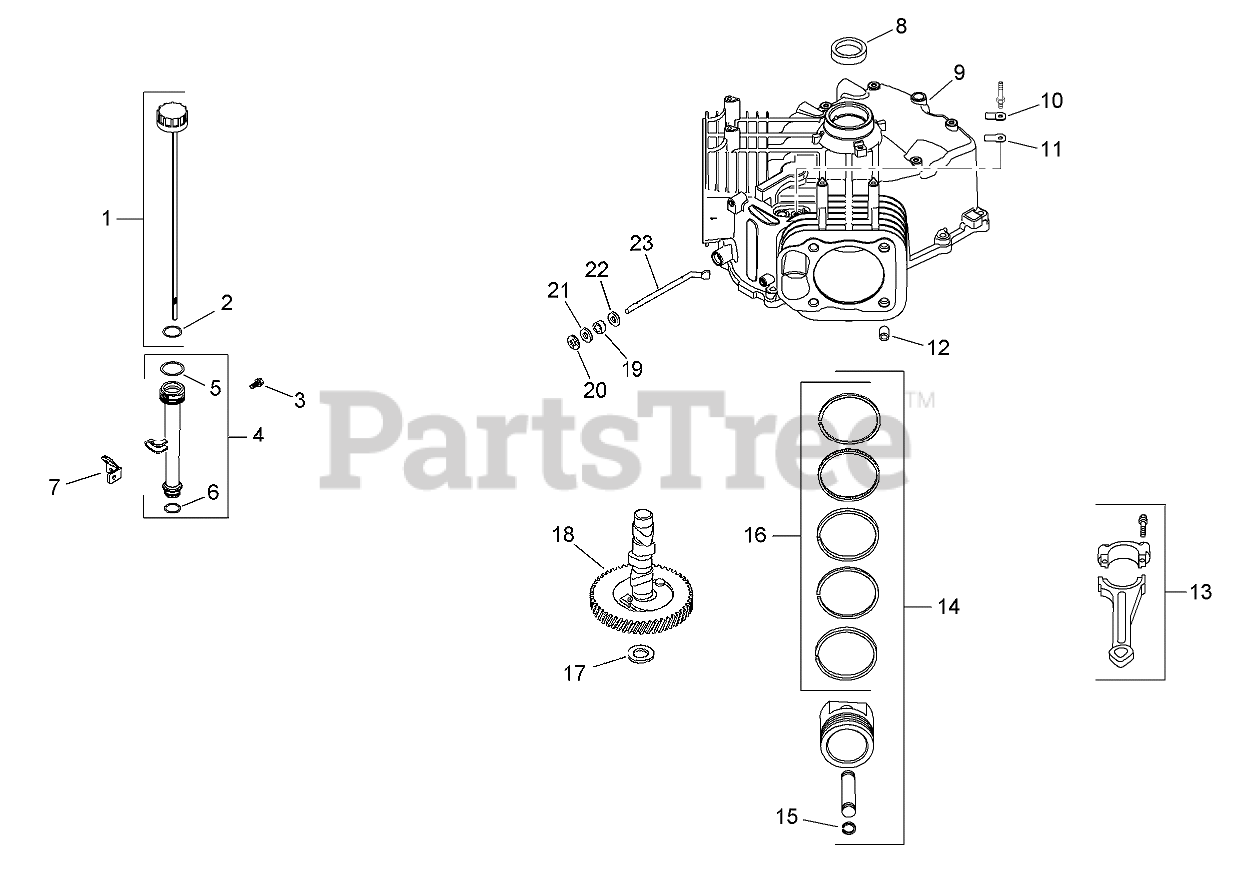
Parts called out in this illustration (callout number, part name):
1	Dipstick ASM (INCLUDES 21, 22)
2	O-RING (DIPSTICK)
3	SCREW-FLG, THD FRM (M5X0.8X13)
4	OIL FILL TUBE KIT
5	O-RING (UPPER OIL FILL TUBE)
6	O-RING (LOWER OIL FILL TUBE)
7	BRACKET-TUBE, OIL FILL
8	SEAL-OIL (HELIX LIP)
9	SHORTBLOCK (SV710-740 REPLACEMENT)
10	RETAINER-REED, BREATHER
11	REED-BREATHER
12	PIN-LOCATING
13	ROD-CONNECTING (STD)
14	PISTON AND RING KIT (STD)
14	PISTON W/RING SET (.25)
14	PISTON W/RING SET (.08)
15	RETAINER-PIN, PISTON
16	Ring Set (.25)
16	Ring Set (STD)
17	SHIM-CAMSHAFT (WHITE .028)
17	SHIM-CAMSHAFT (BLUE .03)
17	SHIM-CAMSHAFT (RED .032)
17	SHIM-CAMSHAFT (YELLOW .034)
17	SHIM-CAMSHAFT (GREEN .036)
17	SHIM-CAMSHAFT (GRAY .038)
17	SHIM-CAMSHAFT (BLACK .04)
18	CAMSHAFT KIT
19	SEAL-CROSS SHAFT, GOVERNOR
20	RETAINER-RING
21	WASHER-FLAT (9MM)
22	WASHER-FLAT (11/32)
23	SHAFT-CROSS, GOVERNOR
